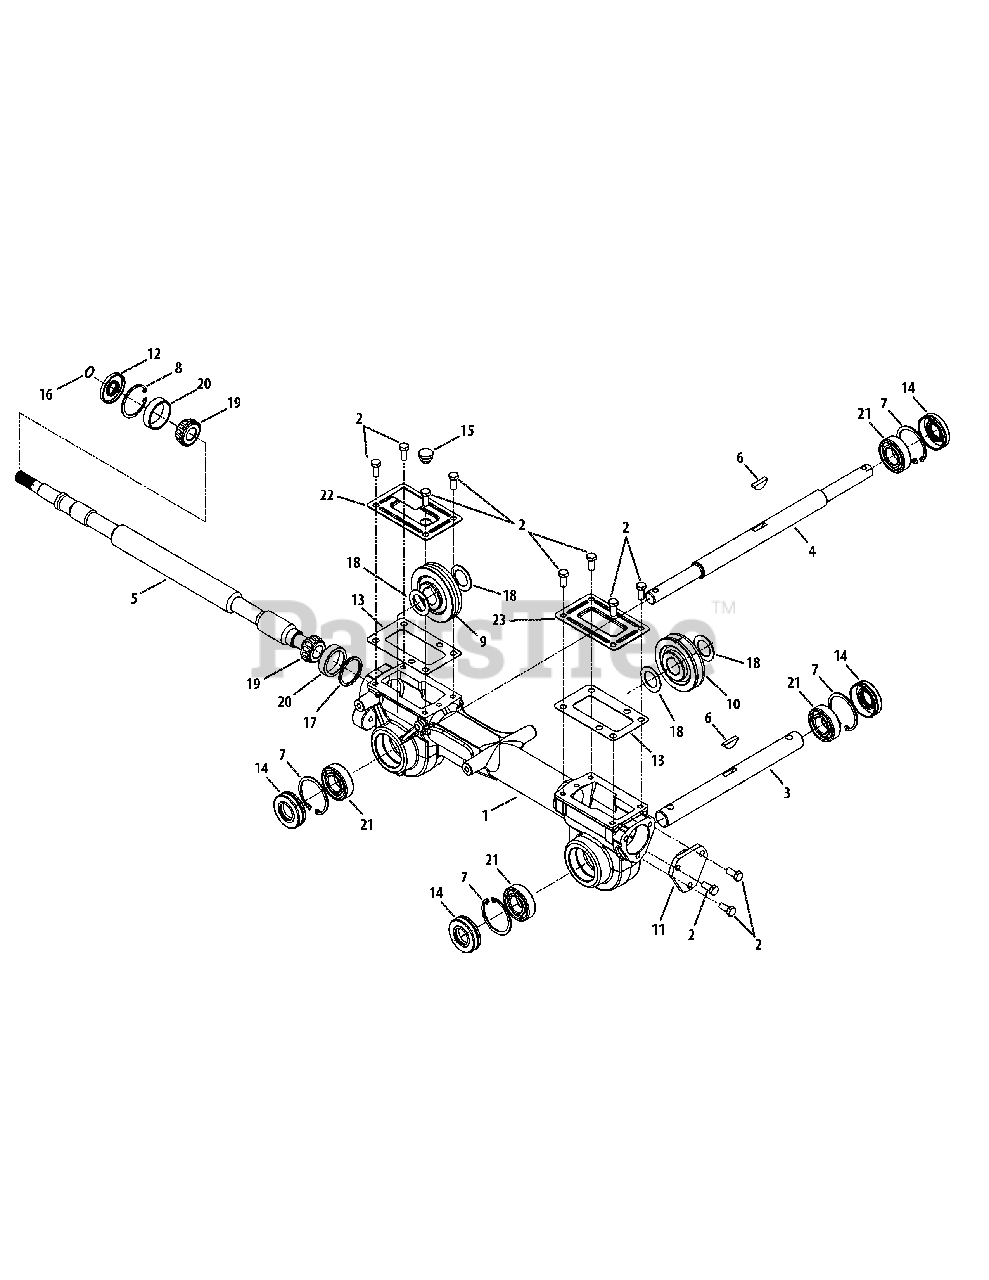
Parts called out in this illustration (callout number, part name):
1	Housing, Transmission
2	Hex Screw, 5/16-18, .75, Gr5
3	Shaft, Tiller
4	Shaft, Wheel
5	Shaft, Worm
6	Key, Hi Pro .25 x 1.062
7	Retaining Ring
8	Retaining Ring, Int
9	Worm Gear, 61t, RH
10	Worm Gear, 30t, LH
11	Bearing Cover
12	Seal, Oil, .750 Shaft x 1.783 Bore
13	Gasket, Gear Housing
14	Seal, Oil, 1.00 Shaft x 2.00 Bore
15	Rubber Plug, Oil
16	Wire Ring
17	Washer, Flat, 1.50 x 1.75 x .062
17	Washer, Flat, 1.50 x 1.75 x .005
17	Washer, Flat, 1.50 x 1.75 x .03
17	Washer, Flat, 1.50 x 1.75 x .010
18	Washer, Flat, 1.010 x 1.56 x .060
19	Cone Bearing
20	Bearing Cup
21	Ball Bearing
22	Cover, Transmission
23	Cover, Transmission
